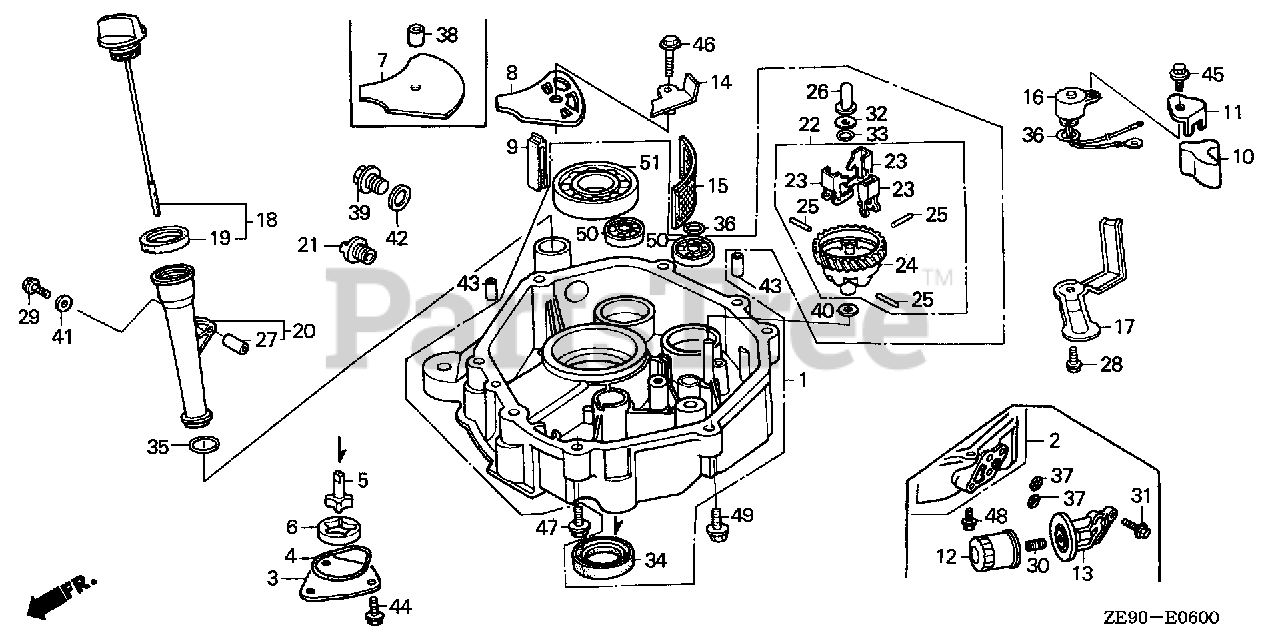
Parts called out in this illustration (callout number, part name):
1	PAN ASSY., OIL (NOT AVAILABLE)
1	PAN ASSY., OIL
3	COVER, OIL PUMP
4	O-RING, PUMP COVER
5	ROTOR (INNER)
6	ROTOR, OIL PUMP (OUTER)
8	PLATE, OIL FILTER
9	RUBBER, OIL RETURN
10	STOPPER, OIL
11	PLATE, OIL STOPPER
14	PLATE, SUCTION
15	SCREEN, OIL FILTER
16	SWITCH, OIL LEVEL
17	PROTECTOR, SWITCH
18	CAP ASSY., OIL FILLER
19	GASKET, OIL FILLER CAP
20	EXTENSION, OIL FILLER
22	GOVERNOR ASSY.
22	GOVERNOR ASSY. (NOT AVAILABLE)
23	WEIGHT, GOVERNOR
24	HOLDER, GOVERNOR WEIGHT
25	PIN, GOVERNOR WEIGHT
26	SLIDER, GOVERNOR
27	COLLAR, EXTENSION
28	BOLT, FLANGE (6X12) (CT200)
29	BOLT, FLANGE (6X35) (CT200)
32	WASHER (6X16)
33	CLIP, GOVERNOR HOLDER
34	OIL SEAL (35X52X8)
35	O-RING (22.1X2.2)
36	O-RING (11.8X2.4)
39	BOLT, DRAIN PLUG (20MM)
40	WASHER, PLAIN (6MM)
41	WASHER, PLAIN (6MM)
42	WASHER, DRAIN PLUG (20MM)
43	PIN, DOWEL (8X12)
43	PIN A, DOWEL (8X12)
44	BOLT, FLANGE (6X12)
45	BOLT, FLANGE (6X16)
46	BOLT, FLANGE (6X25)
47	BOLT, FLANGE (8X40)
48	BOLT, FLANGE (8X40)
48	BOLT, FLANGE (8X60)
49	BOLT, FLANGE (8X40)
50	BEARING, RADIAL BALL (6202)
51	BEARING, RADIAL BALL (6207)
